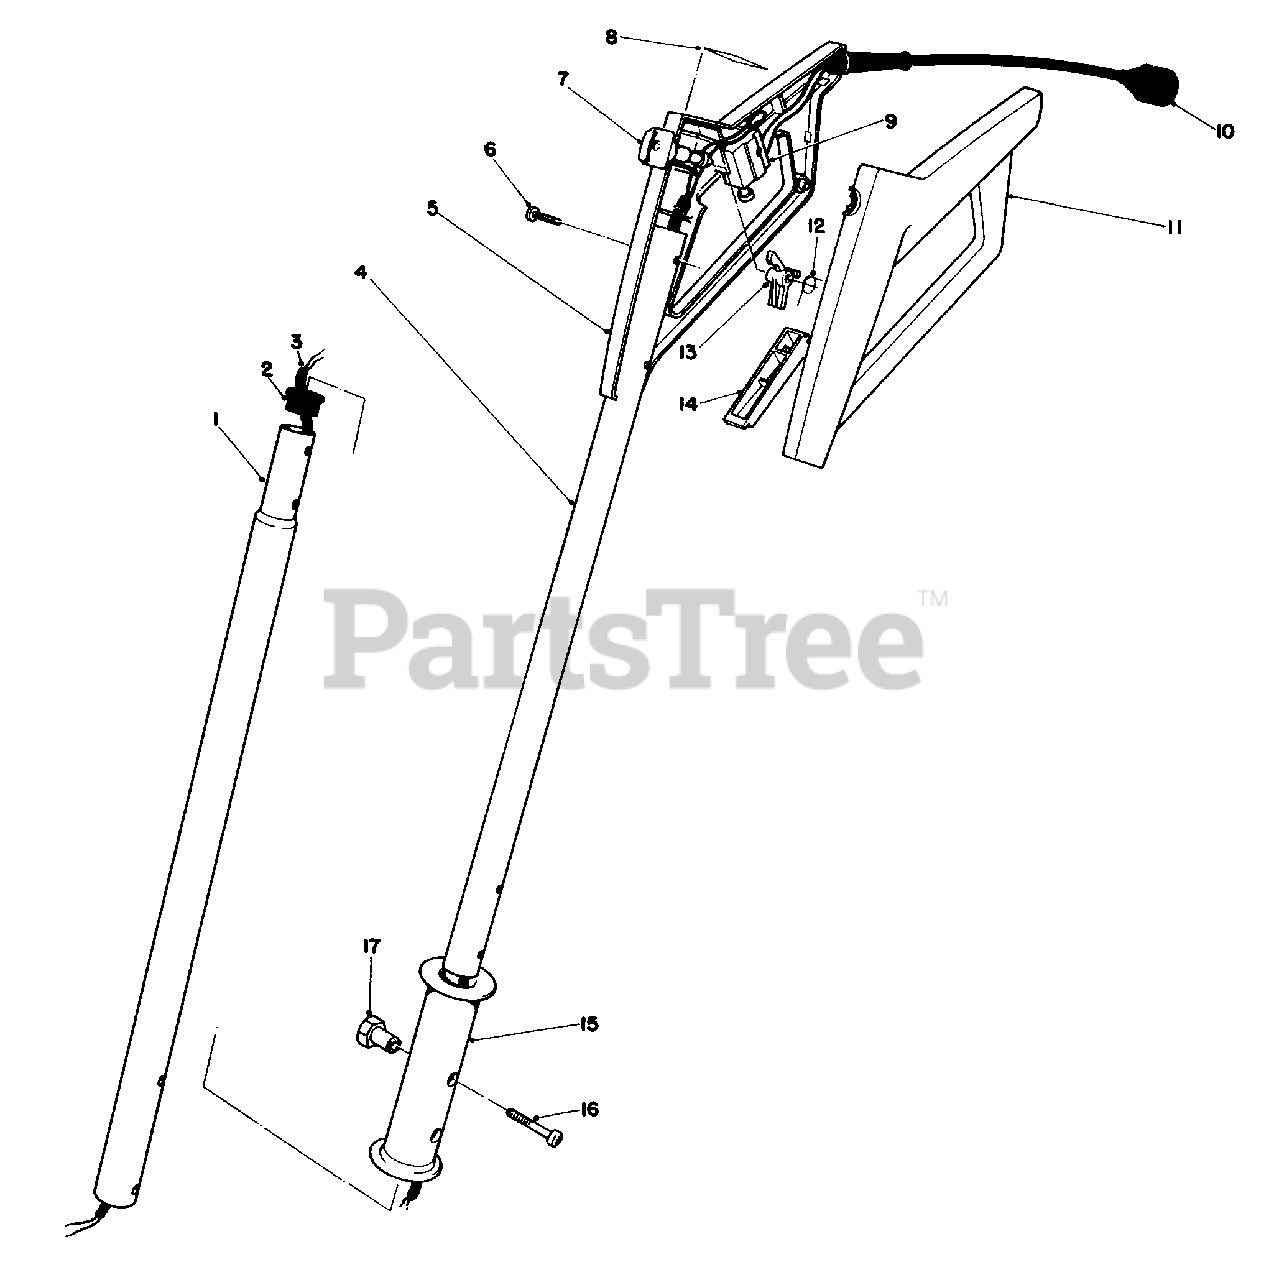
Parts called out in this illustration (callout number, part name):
1	Tube-Handle, Lower
2	Bushing, Heyco
3	Wire Harness
4	Tube-Handle, Upper
5	Control Grip, R.H.
6	Plastite Screw
8	Decal-Control Grip
10	Cord, Supply
11	Control Grip, L.H.
14	Switch Bar
15	Handle Grip
16	Screw, Special
17	Nut, Hex Special
